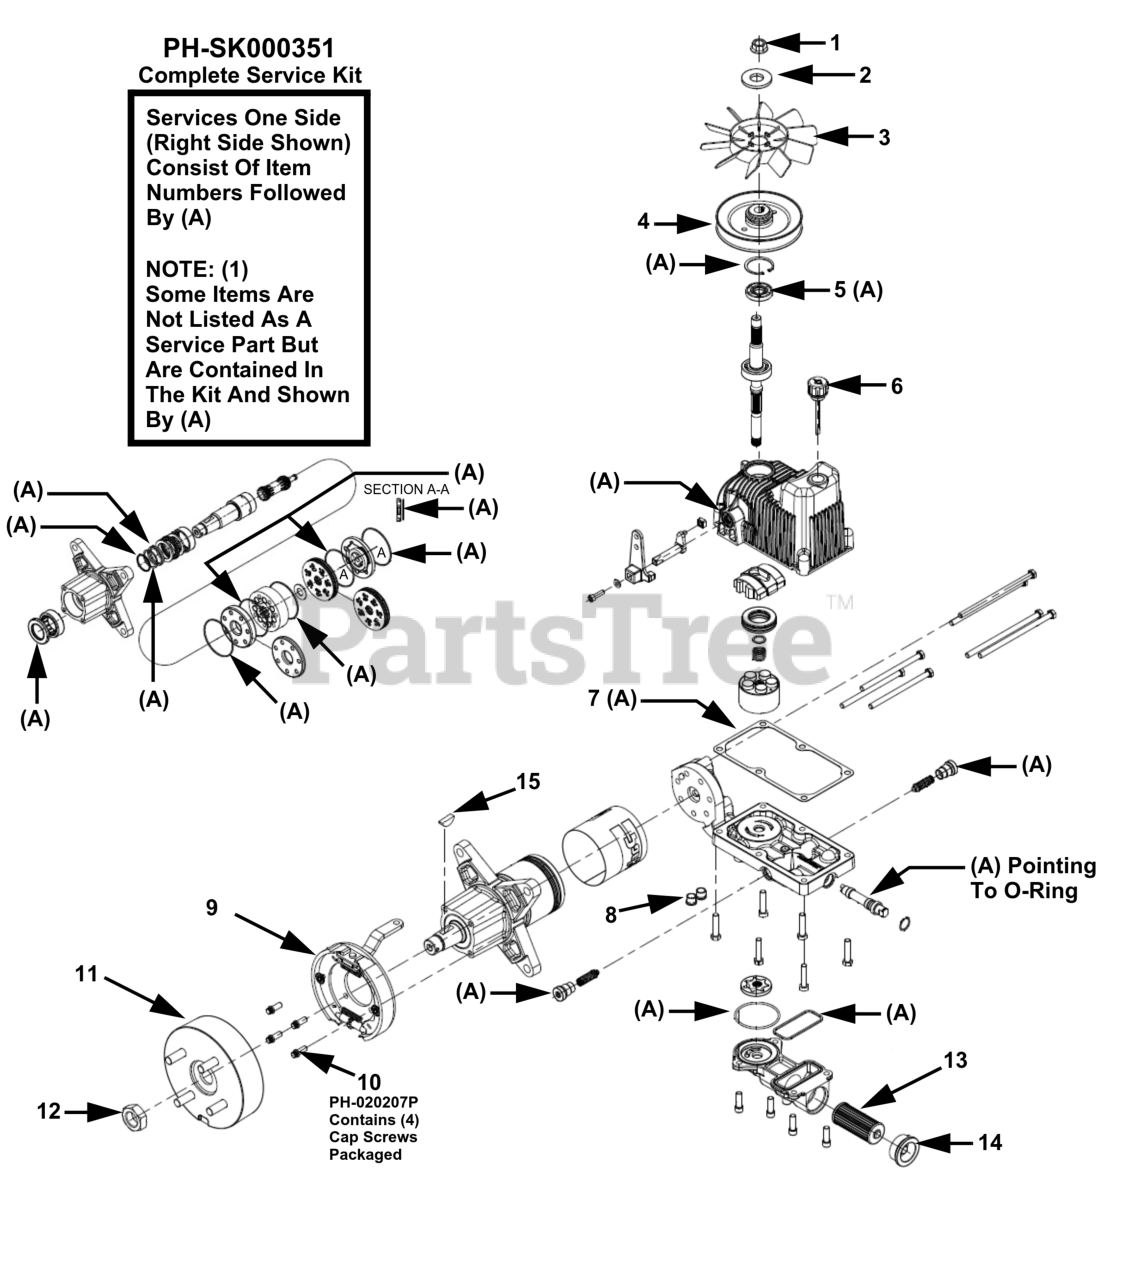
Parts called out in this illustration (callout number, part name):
1	NUT-FLANGE 1/2-20
2	FAN SPACER
4	PULLEY (SPLINED)
6	BREATHER
8	PLUG-MAGNETIC HEX
9	BRAKE ASSEMBLY-ON HOLE LEVER
10	SCREW-CAP (QTY 4)
11	DRUM-4 BOLT BRAKE
12	LOCK NUT - 1-20
14	PLUG & O-RING ASSE
15	WOODRUFF KEY
A	COMPLETE SEAL SERVICE KIT
